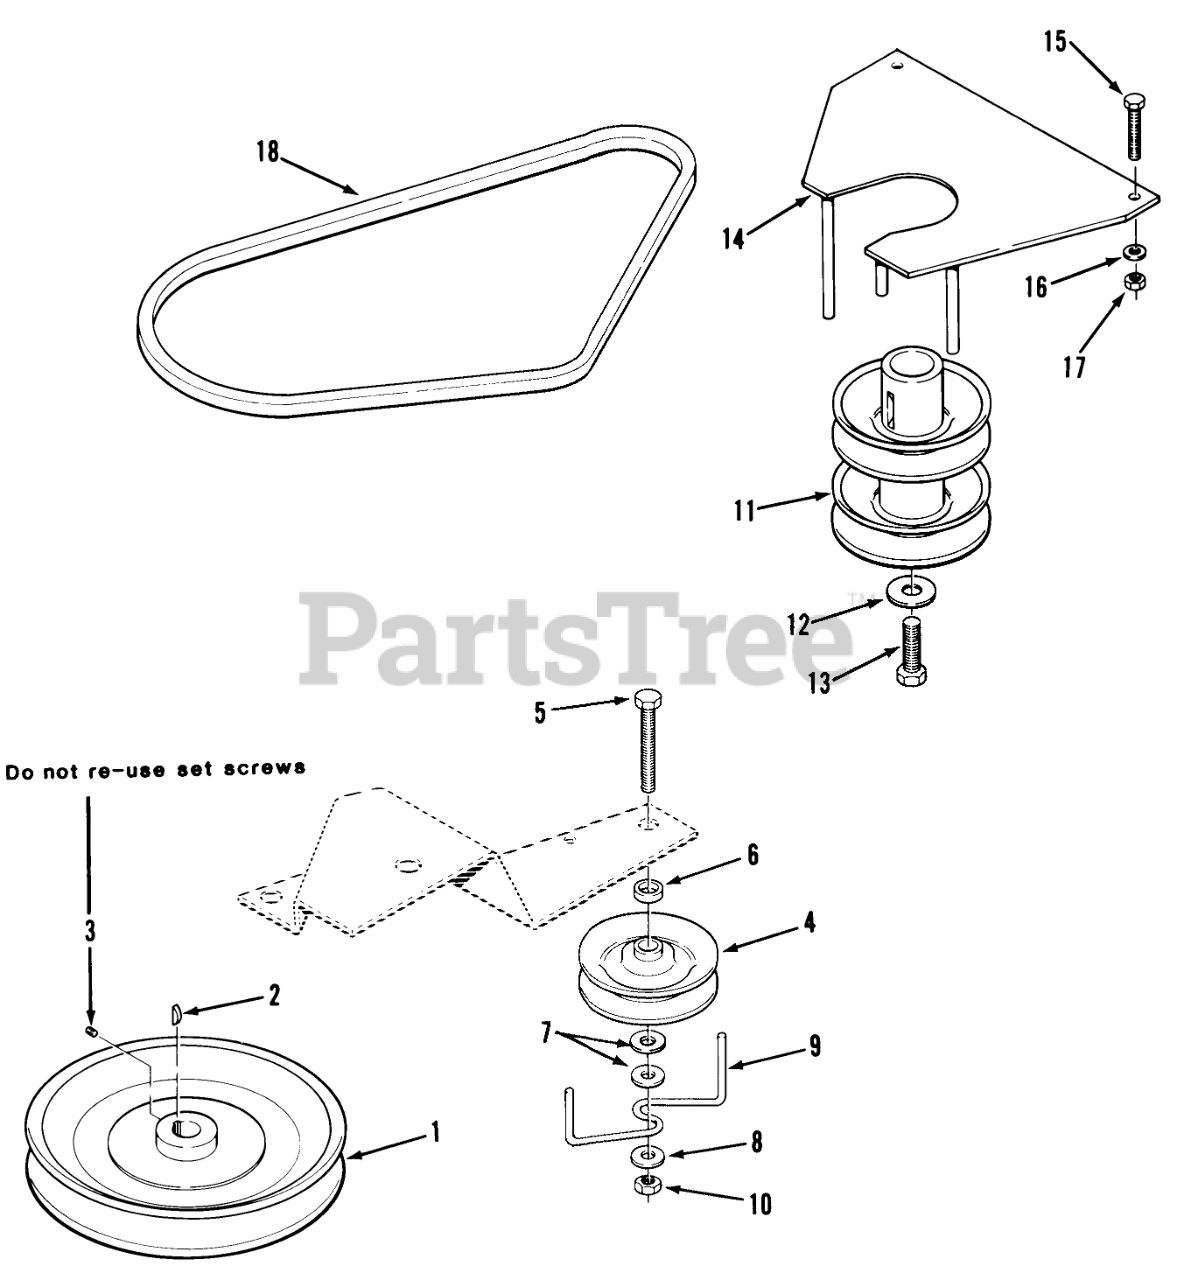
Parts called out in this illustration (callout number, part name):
1	PULLEY TRANSMISSION
2	KEY-HI-PRO
3	Set Screw
4	PULLEY-IDLER STATION
5	Bolt
6	SPACER
7	Washer
8	Washer
9	GUIDE - BELT
10	NUT-HEX, JAM
11	PULLEY ENGINE
12	WASHER
13	HEX HD CAP SCREW
14	ASSY BELT GUIDE R
15	HHCS
16	WASHER 5/16 SAE
17	Nut
18	Transmission Drive Belt
